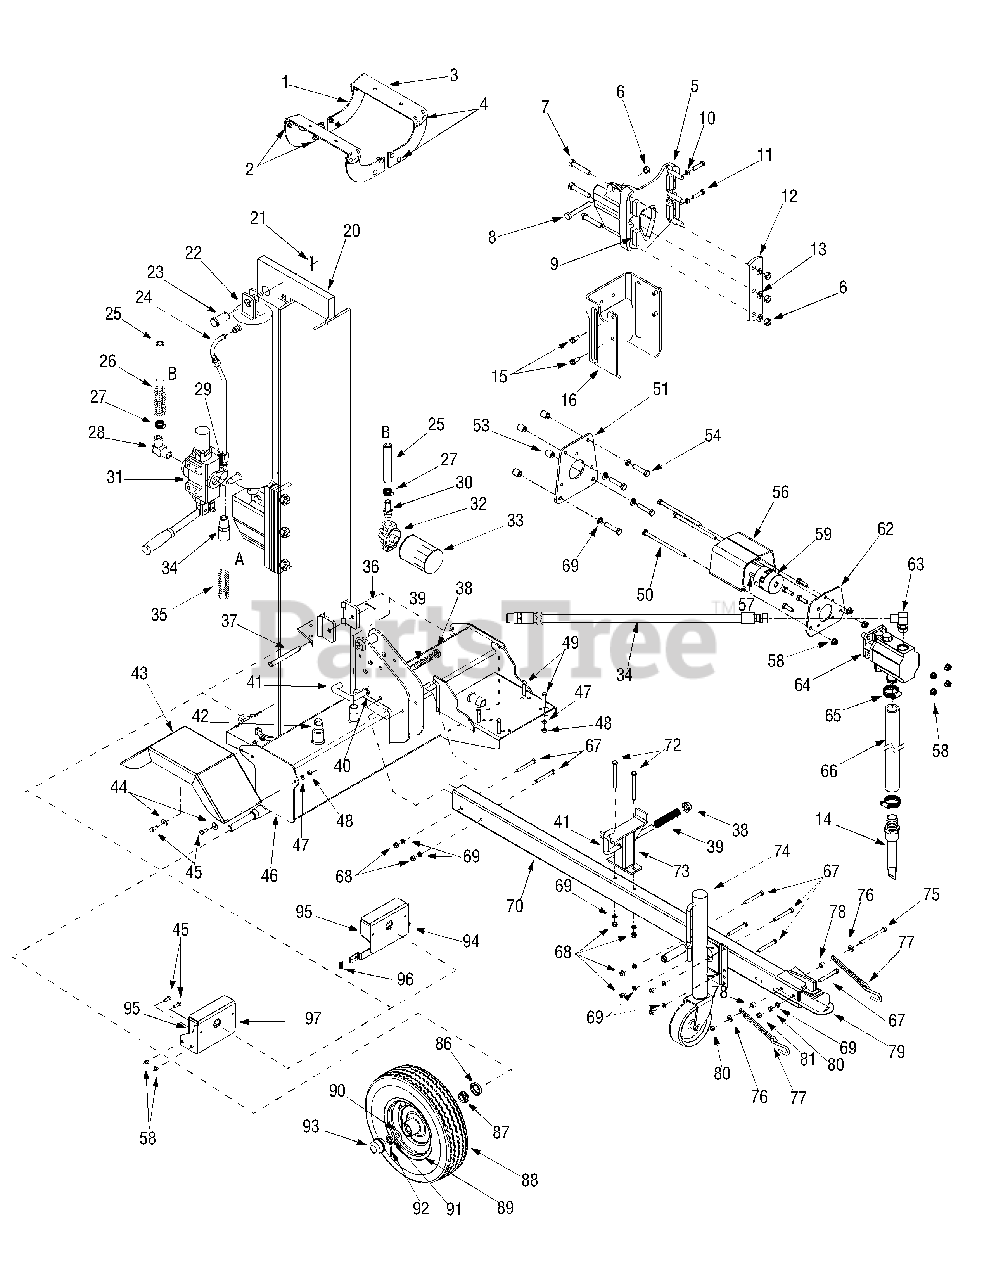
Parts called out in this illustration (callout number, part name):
4	Carriage Bolt 3/8-16 x 1.0
5	Wedge Assembly
6	Lock Nut 1/2-13
7	Hex Cap Screw 1/2-20 x 2.75
8	Hex Cap Screw 1/2-13 x 3.25
9	Adjustable Gib
10	Hex Jam Nut 3/8-24
11	Hex Cap Screw 3/8-24 x 1.5
13	Lock Washer 1/2
14	Inlet Filter
15	Hex Washer Screw 3/8-16 x 1.0
22	Kit Seal 5.0" for Best Metals cylinder 718-0313
22	Hydraulic Cylinder
22	Kit Seal 5.0" for XINGHUI cylinder 718-0313A
22	Kit Seal 5.0" for ENERGY cylinder 718-0313A
23	Clevis Pin
24	Hydraulic Tube
25	Return Hose 3/4" ID x 44"
26	Hose Guard
27	Hose Clamp 5/8"
28	Return Elbow
29	90 Degree Solid Male Adapter
30	3/4" Hose Adapter
32	Filter Housing
33	Oil Filter
34	High Pressure Hydraulic Hose
35	Hose Guard
36	Cotter Pin 1/8"
37	Hinge Pin 1/2 x 4.8" Lg.
39	Compression Spring 4"
40	Flat Washer .635 ID x .93 OD
41	Locking Rod
42	Vented Dipstick
44	Flat Washer, .343 x .880 x .062
45	Hex Cap Screw 5/16-18 x .875
46	Frame Assembly 7.0 Gal
47	Lock Washer 5/16
48	Hex Nut 5/16-18
49	Hex Cap Screw 5/16-24 x 1.75
50	Hex Cap Screw 5/16-18 x 5.50
54	Hex Cap Screw 3/8-16 x 1.75
56	Coupling Shield
57	Key
58	Hex Flange Lock Nut, 5/16-18
59	Flex Coupling
59	Coupling .5 Pump Side
59	Coupling 1.0 Engine Side
59	Bushing, Spider Coupling
59	Set Screw
63	Adapter 7/8-14
64	Pump
65	Hose Clamp
66	Suction Hose
67	Hex Cap Screw 3/8-16 x 3.0
68	Hex Nut 3/8-16
69	Lock Washer 3/8
72	Hex Cap Screw 3/8-16 x 4.0
74	Adjustable Jack Stand
75	Hex Cap Screw 3/8-16 x 4.25
76	Flat Washer .385 ID x .870 OD
77	Chain
79	Hitch Coupler, 2-inch
80	Lock Nut 3/8-16
81	Hex Jam Nut 3/8-16
86	Bearing Seal
87	Bearing Cone
88	Wheel Assembly with bearing cones & seal
88	Tire 4.80 X 8
88	Valve
89	Rim Assembly with bearing cups only
90	Flat Washer .76" ID x 1.5" OD
91	Slotted Nut 3/4-16
92	Cotter Pin 5/32" x 1-1/4"
96	Nut 1/4-20
